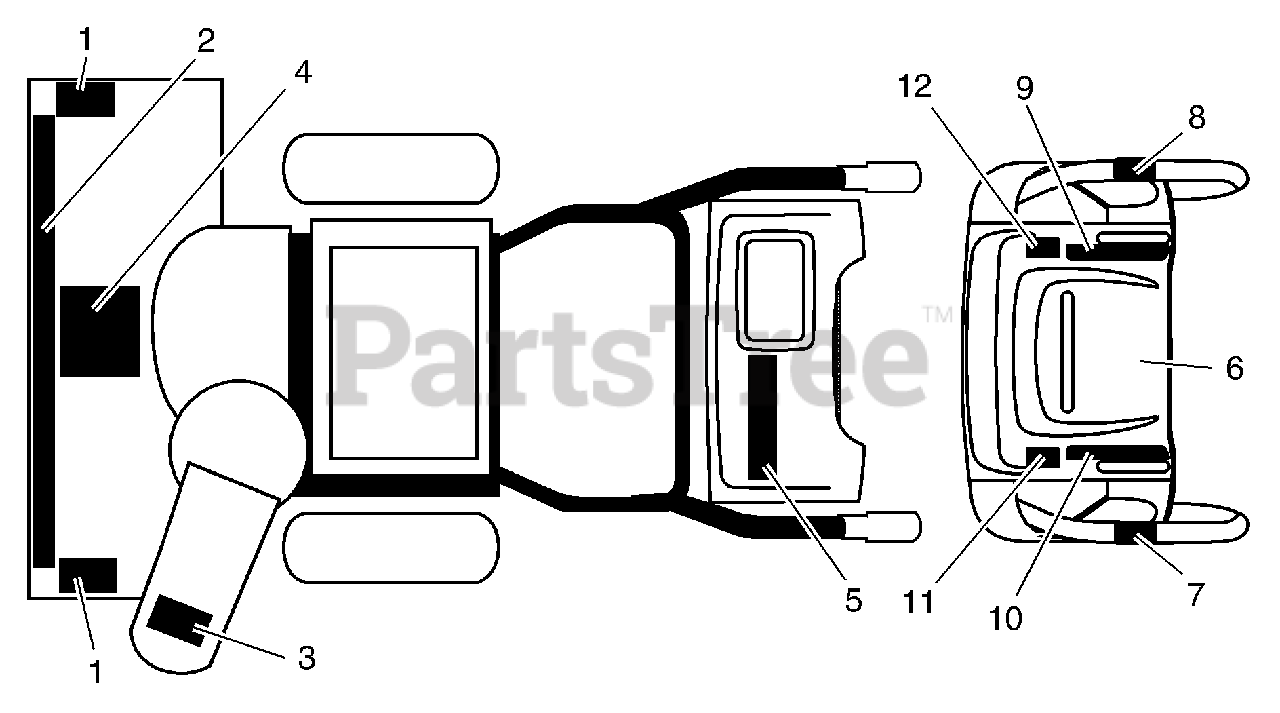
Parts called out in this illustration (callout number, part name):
1	Decal, Danger
2	Decal, Poulan, 8.5 HP / 27" (large)
3	Decal, Danger, Deflector
4	Decal, Danger
5	Decal, Poulan, 8.5 HP / 27" (small)
6	Decal, Instruction
7	Decal, Traction Lever
8	Decal, Auger Lever
9	Decal, Speed Control
11	Decal, LH Power Steering Trigger
12	Decal, RH Power Steering Trigger
